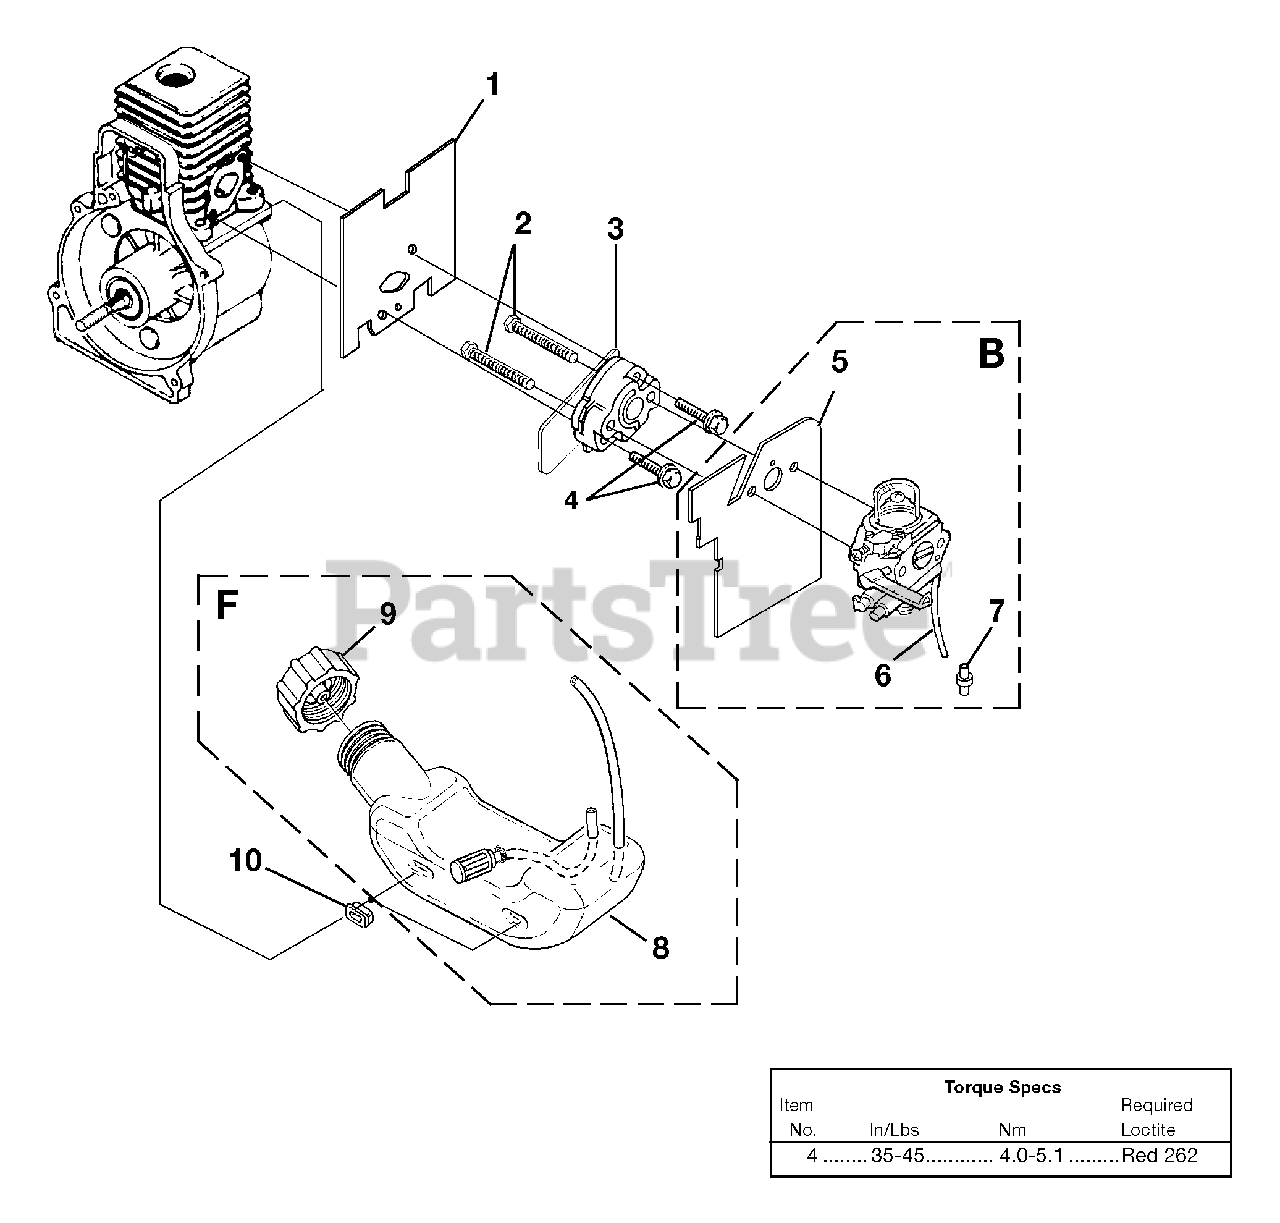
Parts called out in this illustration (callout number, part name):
1	GASKET-Heat Dam
2	SCREW-Machine (10-24 X 2 1/4")
3	HEAT DAM
4	SCREW-Sems (10-24 X 1")
5	GASKET-Carburetor
6	TUBING - Rubber
7	FITTINGS - Inline
8	FUEL TANK
9	FUEL CAP
10	BUMPER - Rubber
B	CARBURETOR KIT
F	FUEL TANK ASSY.
